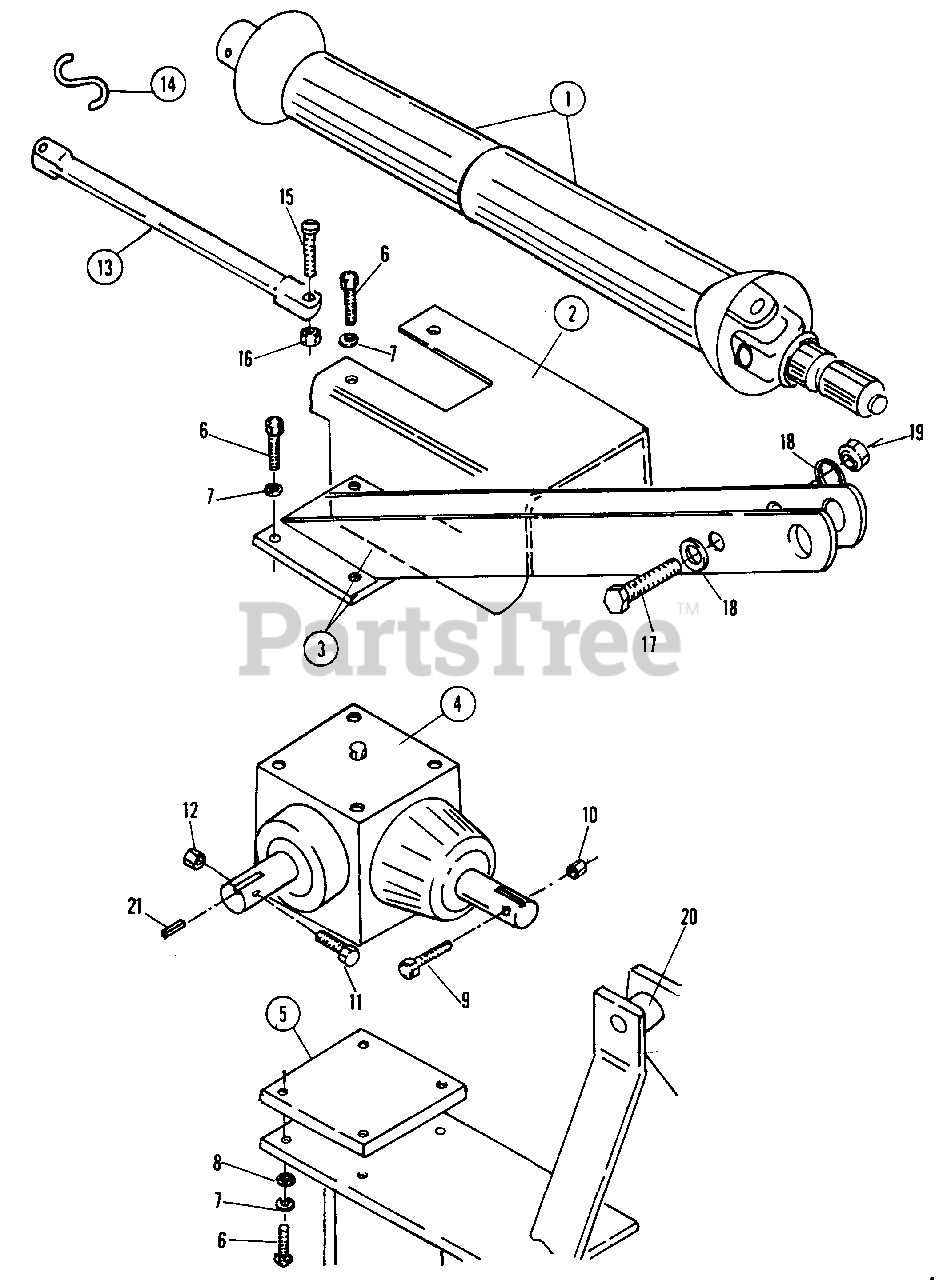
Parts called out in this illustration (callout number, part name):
1	SHAFT, TELESCOPING PTO
2	SHIELD, POWER TAKE OFF
3	LINK, UPPER
4	GEAR BOX, 2:1 RATIO
5	SPACER PLATE, GEAR BOX
6	BOLT, 3/8-16 x 1 -1/4 HEX - GRADE 5
7	LOCKWASHER, 3/8
8	WASHER, 3/8 PLAIN
9	BOLT, 3/8-16 x 2 HEX - GRADE 5
10	LOCKNUT, 3/8-16 HEX
11	BOLT, 1/4-20 x 2-1/2 HEX - GRADE 2
12	LOCKNUT, 1/4-20 HEX
13	STRAP, RUBBER
14	"S" HOOK
15	BOLT, Carriage 1/4C X1-1/4
16	NUT, 1/4-20 HEX
17	SCREW, 1/2-13 x 3-1/2 HEX HEAD CAP - GRADE 5
18	WASHER, 1/2 PLAIN
19	LOCKNUT, 1/2-13 HEX
20	SPACER, MAST
21	KEY, 1/4 SQ. x 1
